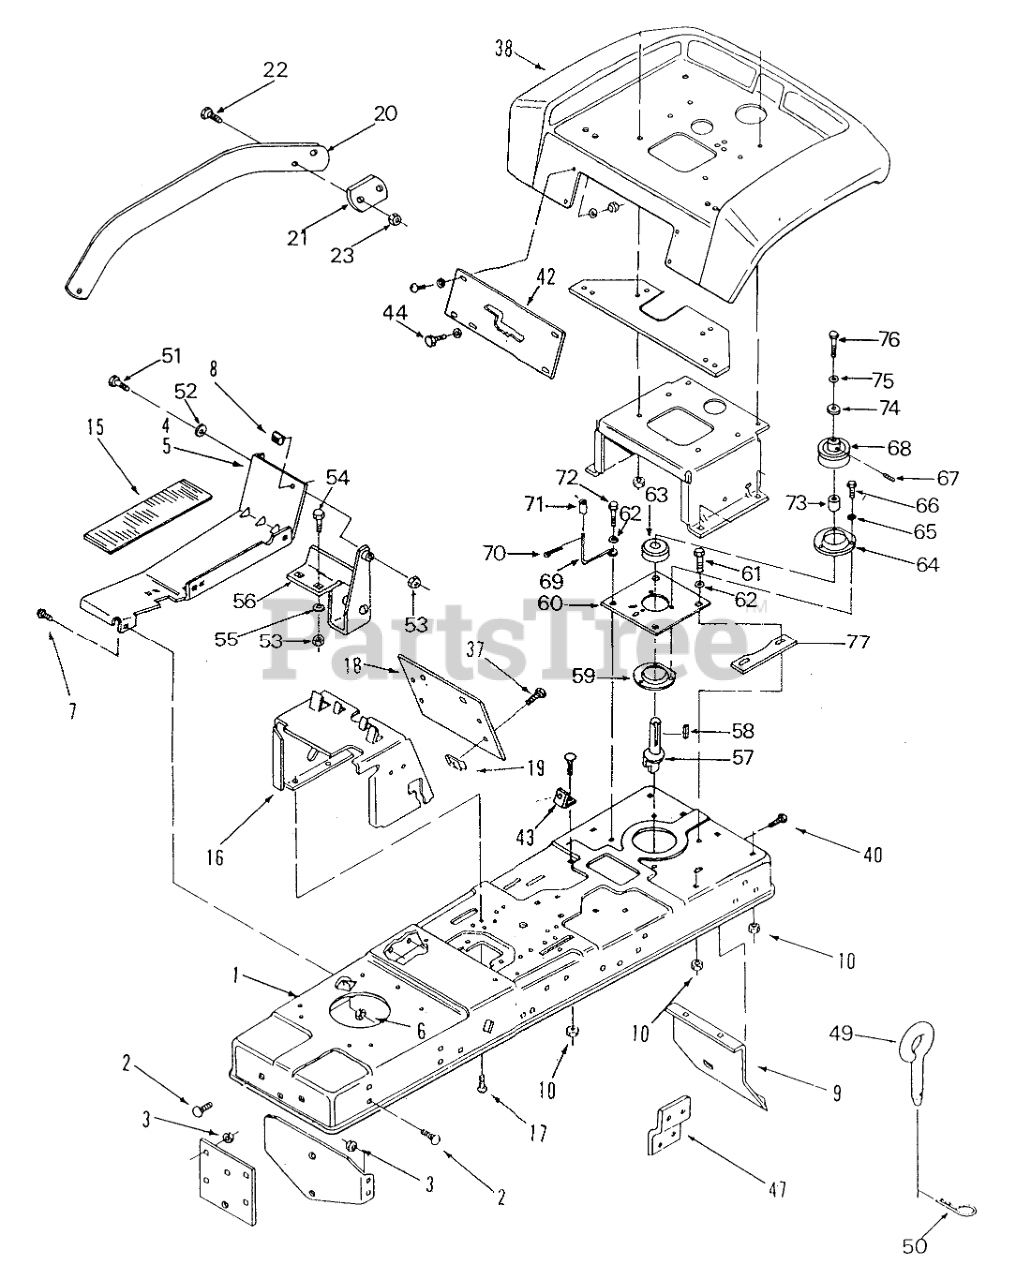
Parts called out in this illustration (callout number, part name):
54	Bolt
55	WASHER 5/16 SAE
56	ASS'Y-BRACKET R.H R
57	SHAFT-DRIVE
58	KEY
59	BEARING-CUP W/NUTS
60	PLATE-MTG R
61	Bolt
62	WASHER 5/16 SAE
63	BEARING-BALL
64	BEARING-CUP
65	Washer
66	Bolt
67	Set Screw 5/16-18 x 3/8
68	PULLEY
69	GUIDE-BELT
70	Cotter Pin
71	SPACER
72	Bolt
73	SPACER SHAFT
74	WASHER
75	LOCKWASHER
76	BOLT
77	SPACER-MTG PLATE R
